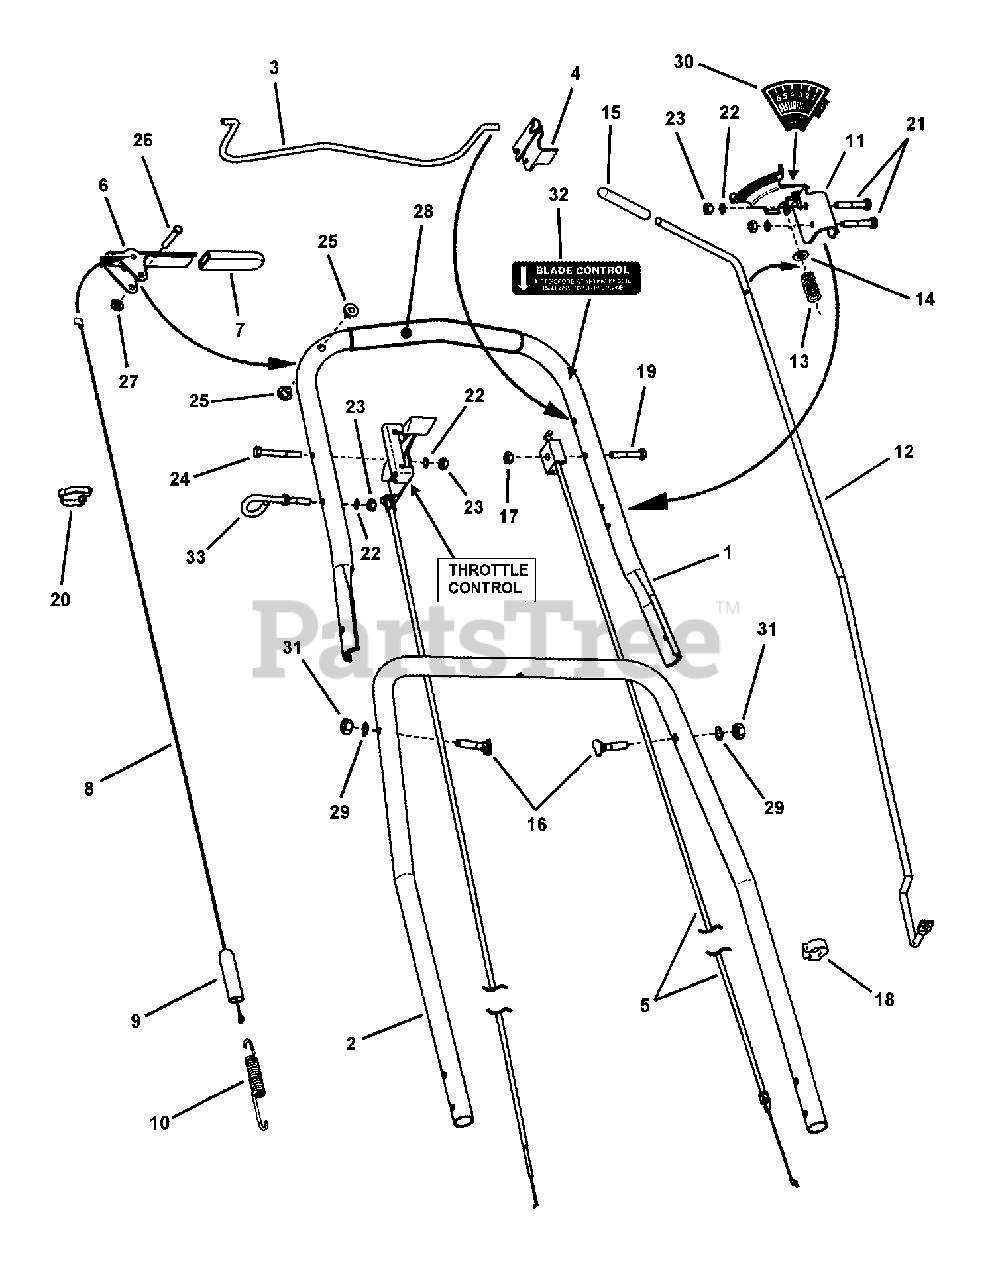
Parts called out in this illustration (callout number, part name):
1	HANDLE, Upper
2	HANDLE, Middle
3	BAIL, OPC Control (12.5" Wide)
3	CLIP, Blade Control (Honda Models)
4	CLIP, Blade Control (Kawasaki & Robin Models)
5	CABLE, Blade Control (47.85/3.93 length)
5	CABLE, Blade Control (46.00/4.12 length)
5	CABLE, Blade Control (46.12/3.50 length)
5	CABLE, Blade Control (44.00/4.16 length)
6	HANDLE, Wheel Drive
7	GRIP, Wheel Drive Handle
8	CABLE, Clutch Pull (Z-bend) (38.31" length)
9	COVER, Vinyl
10	SPRING, Clutch
11	SECTOR, Speed
12	LEVER, Speed Control
13	SPRING, Speed Control
14	WASHER, 3/8" Flat
15	GRIP, Speed Control Handle
16	BOLT, 5/16-18 x 1-1/2" Curved Head Carriage
17	NUT, 1/4-28 Hex Top Lock
18	CLIP, Wiring Harness
19	SCREW, 1/4-28 x 1-3/8" Hex Head Cap GR5
20	CLAMP, 7/8" Double Cable
21	SCREW, 1/4-20 x 1-1/2" Hex Head Cap GR5
22	WASHER, 1/4" Internal Tooth Lock
23	NUT, 1/4-20 Hex
24	SCREW, 1/4-20 x 2" Hex Head Cap GR5
25	BUSHING
26	PIN, 1/4" x 1-1/2" (for clutch handle)
27	PUSH-NUT, 1/4" (for handle pin)
28	FOAM GRIP, 13.5"
28	FOAM GRIP, 12"
29	WASHER, 5/16" Internal Tooth Lock
30	DECAL, Speed Select
31	NUT, 5/16-18 Hex, GR5
32	DECAL, Blade Control
33	GUIDE, Rope (1/4-20 thread)
